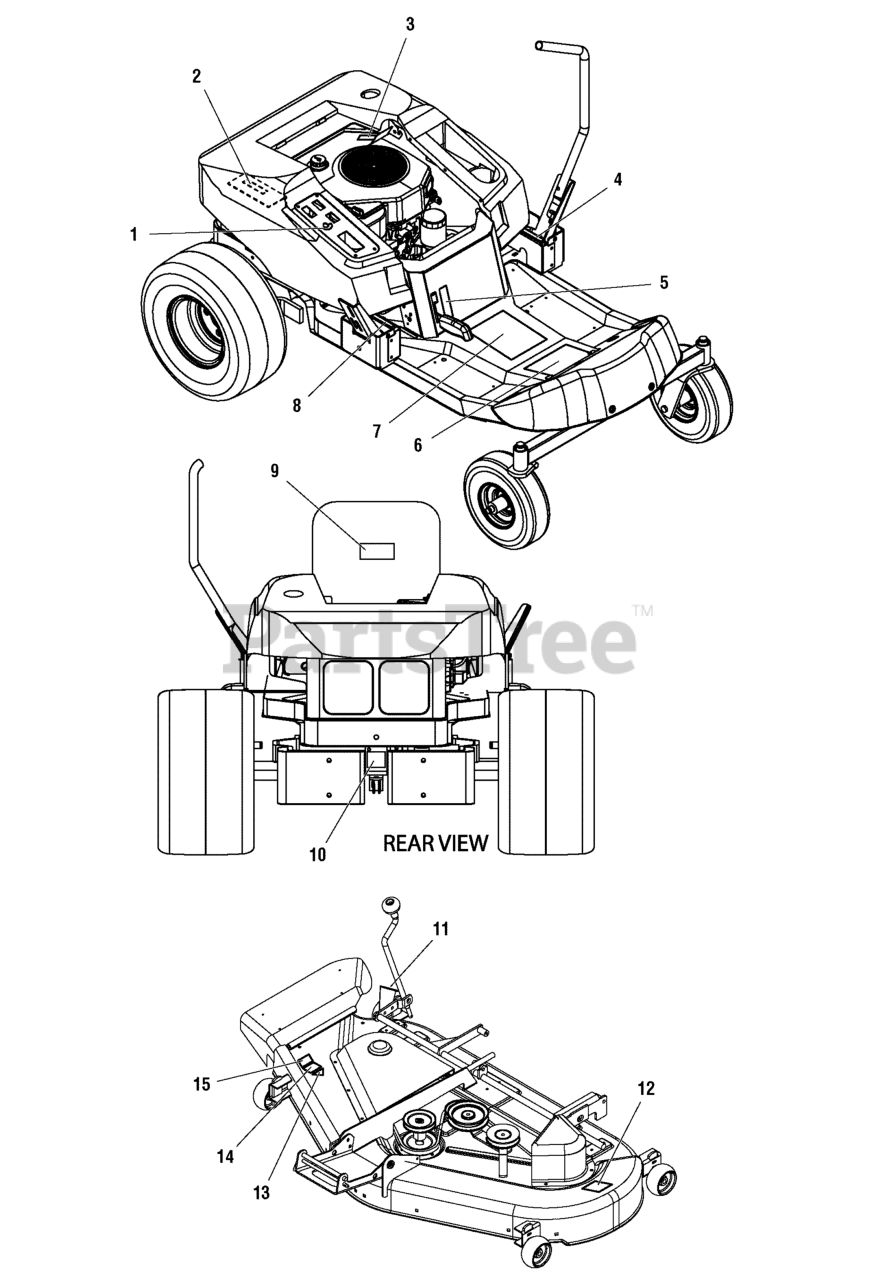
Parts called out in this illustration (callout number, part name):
1	DECAL, Ignition Switch
2	DECAL, Sealed Hydro System
3	DECAL, Do Not Remove Foam Seal
4	DECAL, Motion Control, L.H.
5	DECAL, Parking Brake
6	DECAL, Panel Upper, Operation
7	DECAL, Panel Lower, Warning/Danger & Icon Indicator
8	DECAL, Motion Control, R.H.
9	DECAL, ID Plate
10	DECAL, Transmission Release Valve
11	DECAL, Height of Cut
12	DECAL, Danger (Do Not Put Hands/Feet in Mower)
13	DECAL, OPEI Certified (Not Serviced)
14	DECAL, 44"
15	DECAL, Danger (Do Not Operate With Out Deflector)
